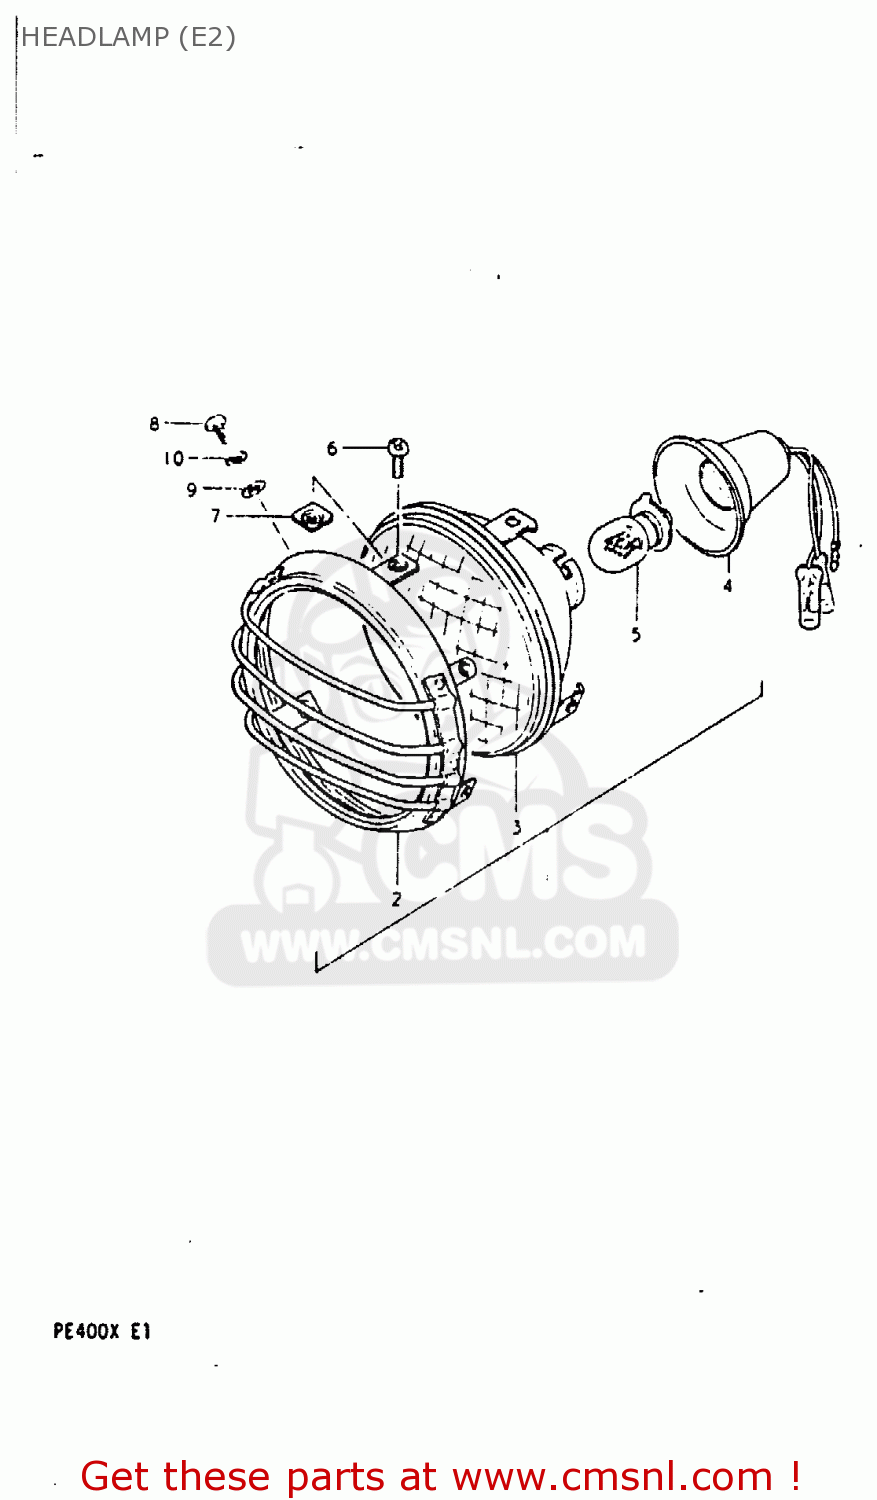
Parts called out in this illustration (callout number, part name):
1	HEADLAMP ASSY
2	RIM,HEADLAMP
3	LAMP UNIT
4	SOCKET,HEADLAMP
5	BULB (7V,18/18W)
6	SCREW
7	NUT
8	SCREW
9	WASHER
10	LOCK WASHER
